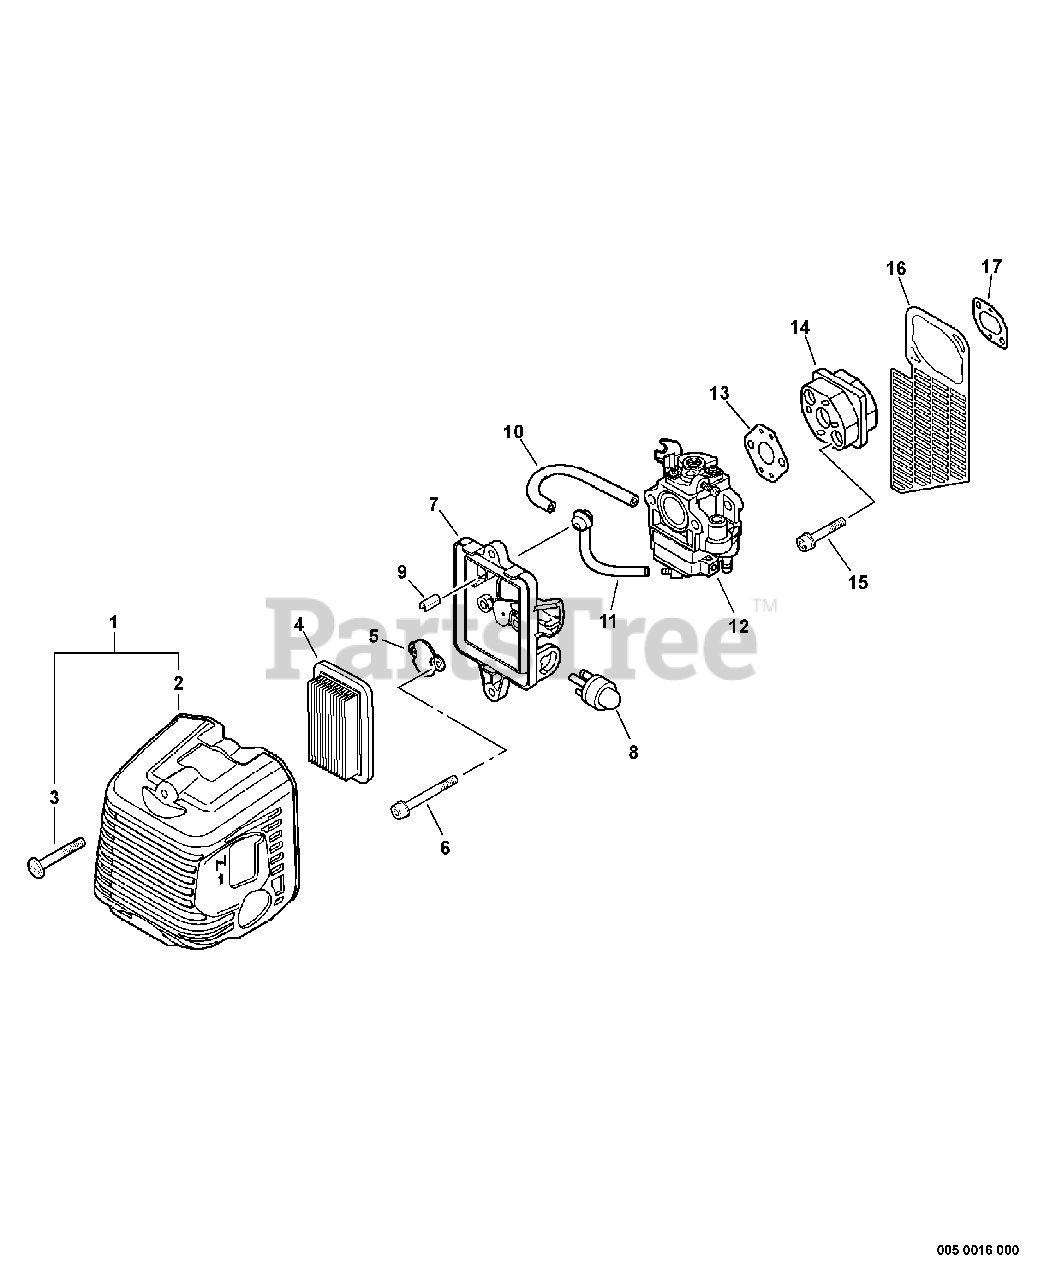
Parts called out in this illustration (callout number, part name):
1	COVER ASSY, AIR FILTER
2	COVER, AIR FILTER
3	SCREW 5×20
4	FILTER, AIR
5	PLATE, PREVENT
6	BOLT 5×55
7	CASE, AIR FILTER
8	BULB, PURGE
9	PIPE, INTAKE
10	PIPE, FUEL 2.4×5×80 BLACK
11	GROMMET, W/VENT PIPE 3×6×105
12	CARBURETOR
13	GASKET, INTAKE
14	INSULATOR, INTAKE
15	BOLT 5×25
16	SHIELD, DEBRIS
17	GASKET, INTAKE
